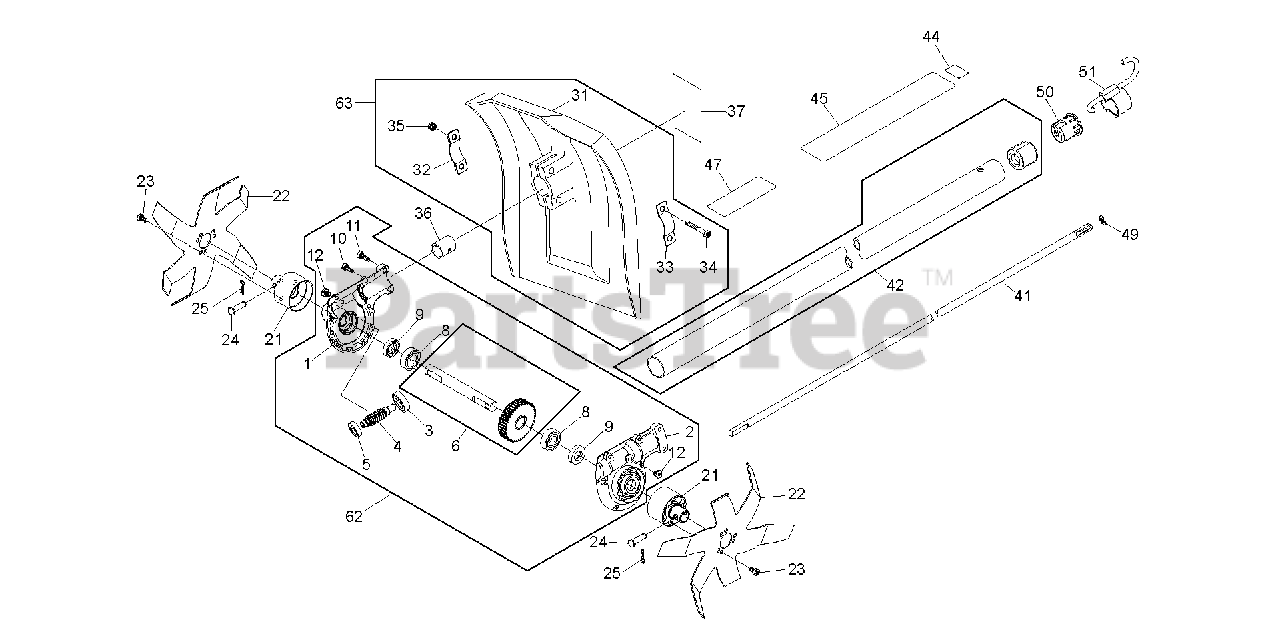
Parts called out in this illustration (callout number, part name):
1	WORM CASE A
2	WORM CASE B
3	BEARING, RADIAL BALL (6301LL)
5	BEARING, RADIAL BALL (6001ZZ)
6	WHEEL, WORM
8	BEARING, RADIAL BALL (6003ZZ)
9	OIL SEAL (TC17307)
10	BOLT, TORX (5X15)
11	BOLT, TORX (6X20)
22	BLADE, CUTTER
23	BOLT, TORX (6X10)
34	BOLT, TORX (6X45)
35	NUT, HARD LOCK (M6)
37	MARK 2, CAUTION
41	SHAFT, DRIVE
44	MARK, ARROW
45	MARK 1, CAUTION
47	MARK, EMBLEM (SSCL)
62	WORM CASE ASSY.
63	COVER ASSY.
